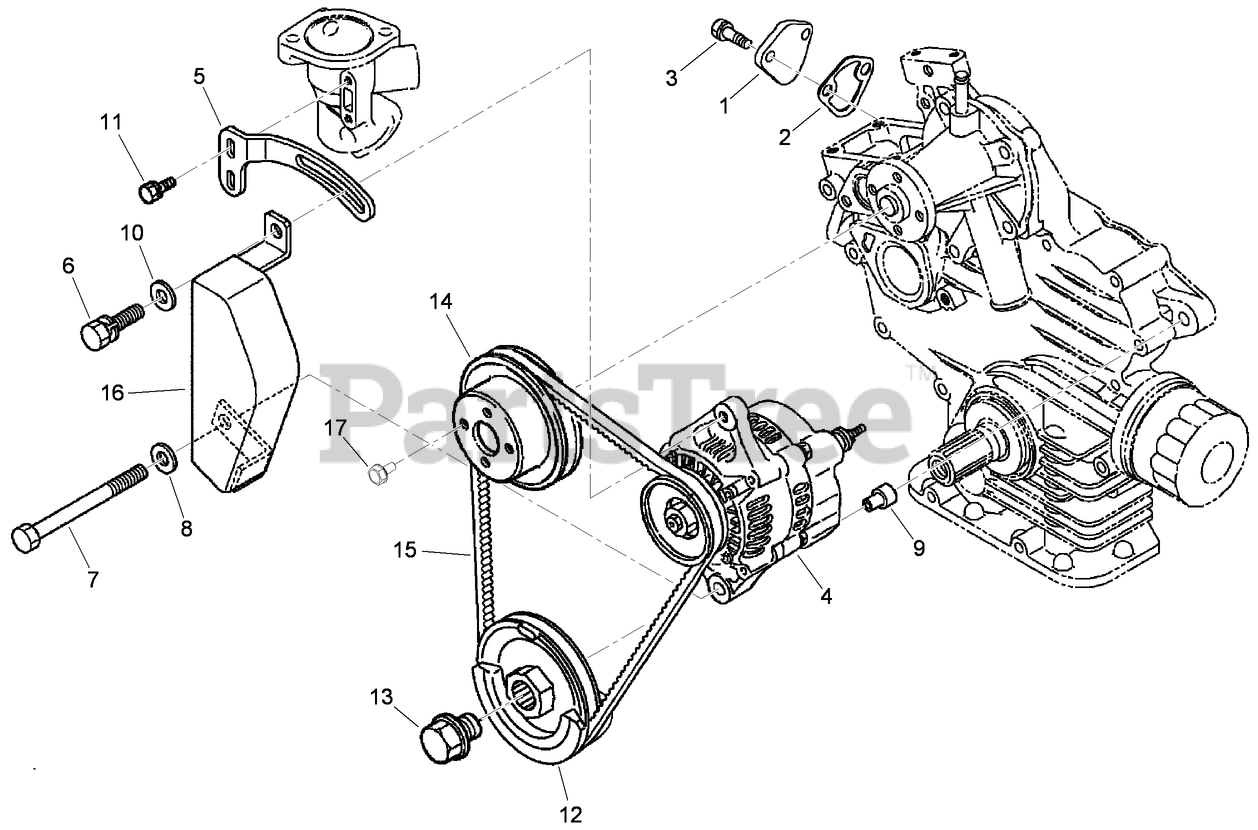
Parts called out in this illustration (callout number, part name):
1	COVER
2	GASKET-PUMP, FUEL
4	ALTERNATOR ASM
5	STAY-ALTERNATOR
8	WASHER-PLAIN
9	COLLAR
10	WASHER-PLAIN
12	PULLEY-DRIVE, FAN
14	PULLEY-FAN
15	BELT-V
17	BOLT-FLANGE
